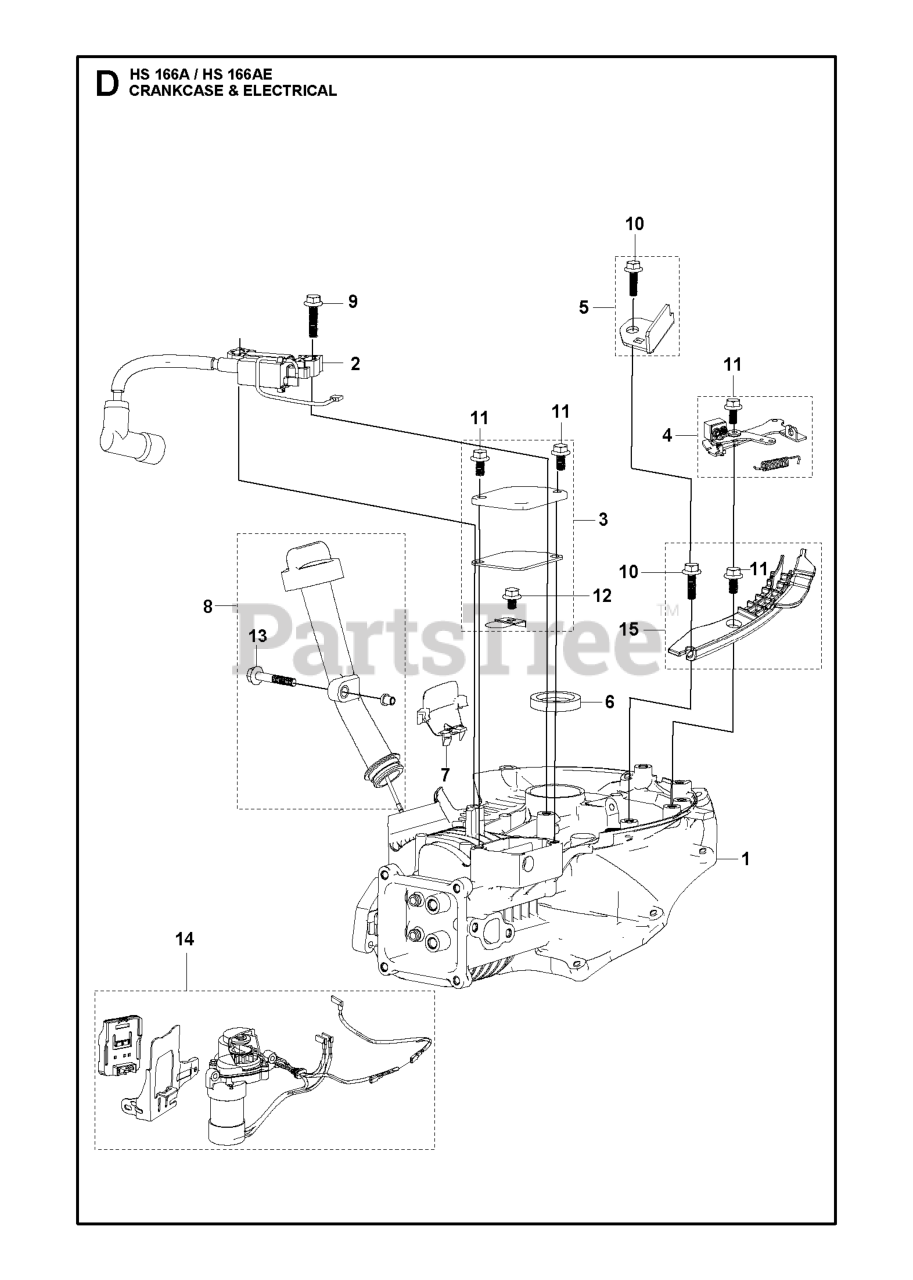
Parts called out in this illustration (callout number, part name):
9	BOLT GB/T 5789: M6 L=25
10	BOLT GB/T 5789: M6 L=20
11	BOLT GB/T 5789: M6 L=12
12	Husqvarna TBD
13	BOLT GB/T 5789: M6 L=35
